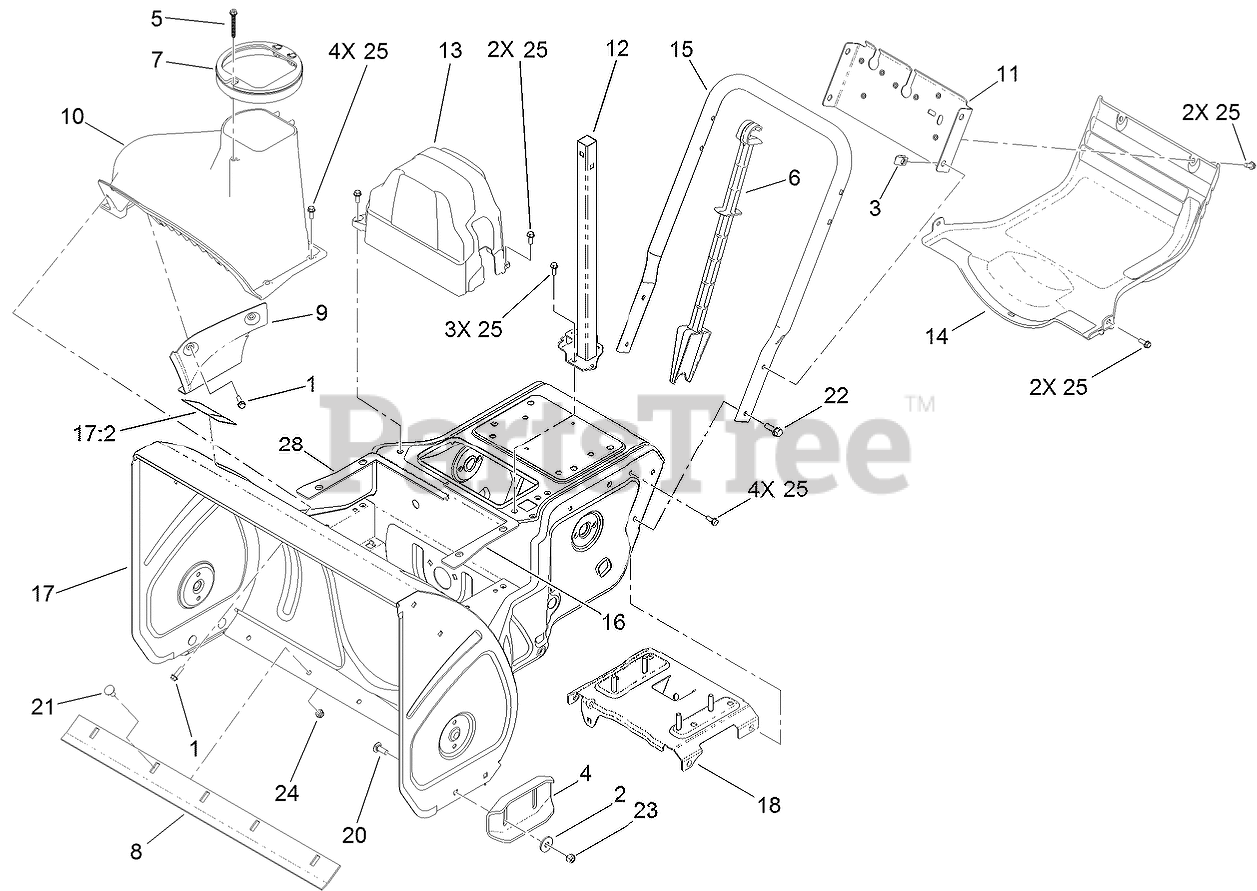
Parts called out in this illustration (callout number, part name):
1	SCREW-HWH
2	WASHER
3	NUT-U
5	SCREW-HWH, PLASTITE
6	STICK-CLEANOUT
7	GUIDE-CHUTE
8	SCRAPER-24 INCH
9	COVER-LINER
11	BRACE-FRAME
12	SUPPORT-CHUTE
13	COVER-BELT
14	COVER-LOWER
15	HANDLE-LOWER
16	SEAL-HOUSING, LH
17	FRAME ASM
17:2	DECAL-DANGER, AUGER
18	PLATE-STUD ENGINE
20	BOLT-CARR
21	SCREW-CARR
22	SCREW-HHF
23	NUT-LOCK, NI
24	NUT-LOCK, NI
25	SCREW-HWH
28	SEAL-HOUSING, RH
